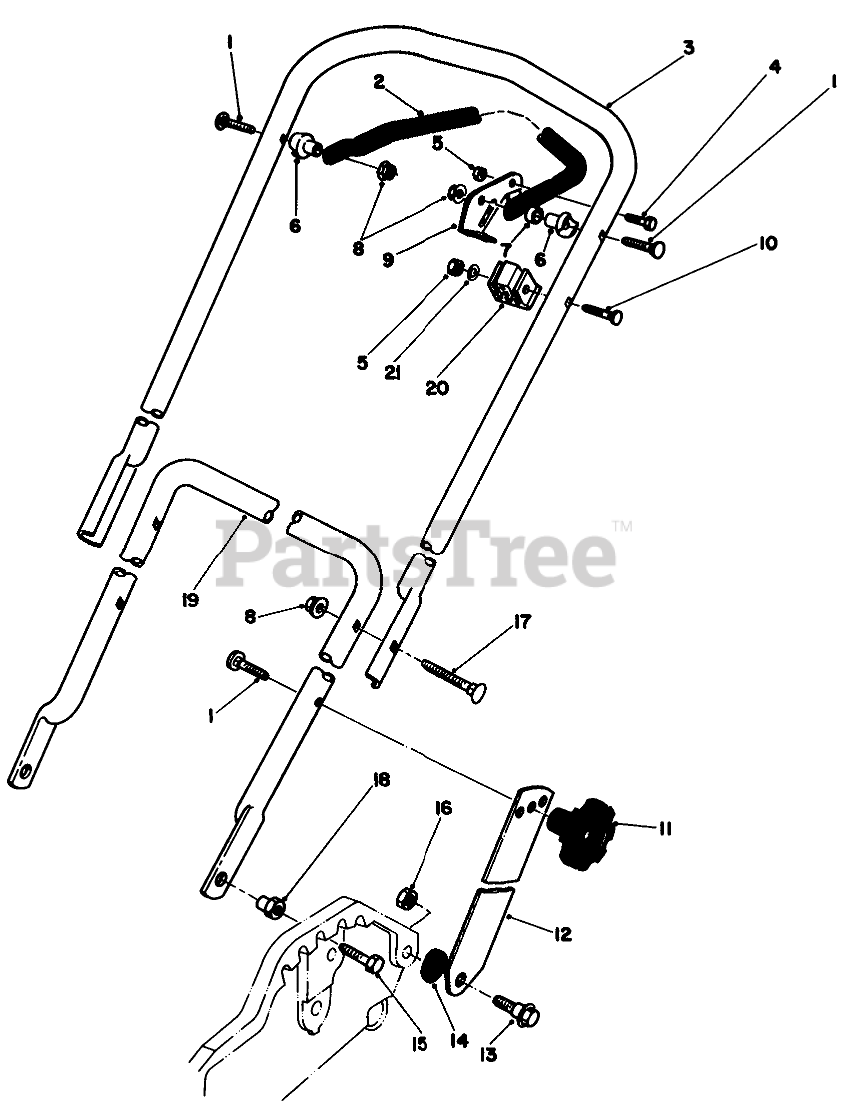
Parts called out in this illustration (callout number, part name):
1	5/16-18 X 2 HNDLE SCREW
2	CONTROL BAR
3	UPPER HANDLE
4	SCREW-HH
5	NUT-LOCK, NI
6	SPACER-SUPPORT
7	SPACER-NYLON
8	NUT-LOCK, NI
9	LEVER-CONTROL
10	HANDLE SCREW
12	Handle Latch
13	SCREW-SHOULDER
14	SPACER
15	SCREW-HH
16	NUT-LOCK, NI
17	SCREW
18	HANDLE PIVOT NUT
19	LOWER HANDLE
20	SUPPORT-CABLE
21	WASHER-FLAT
